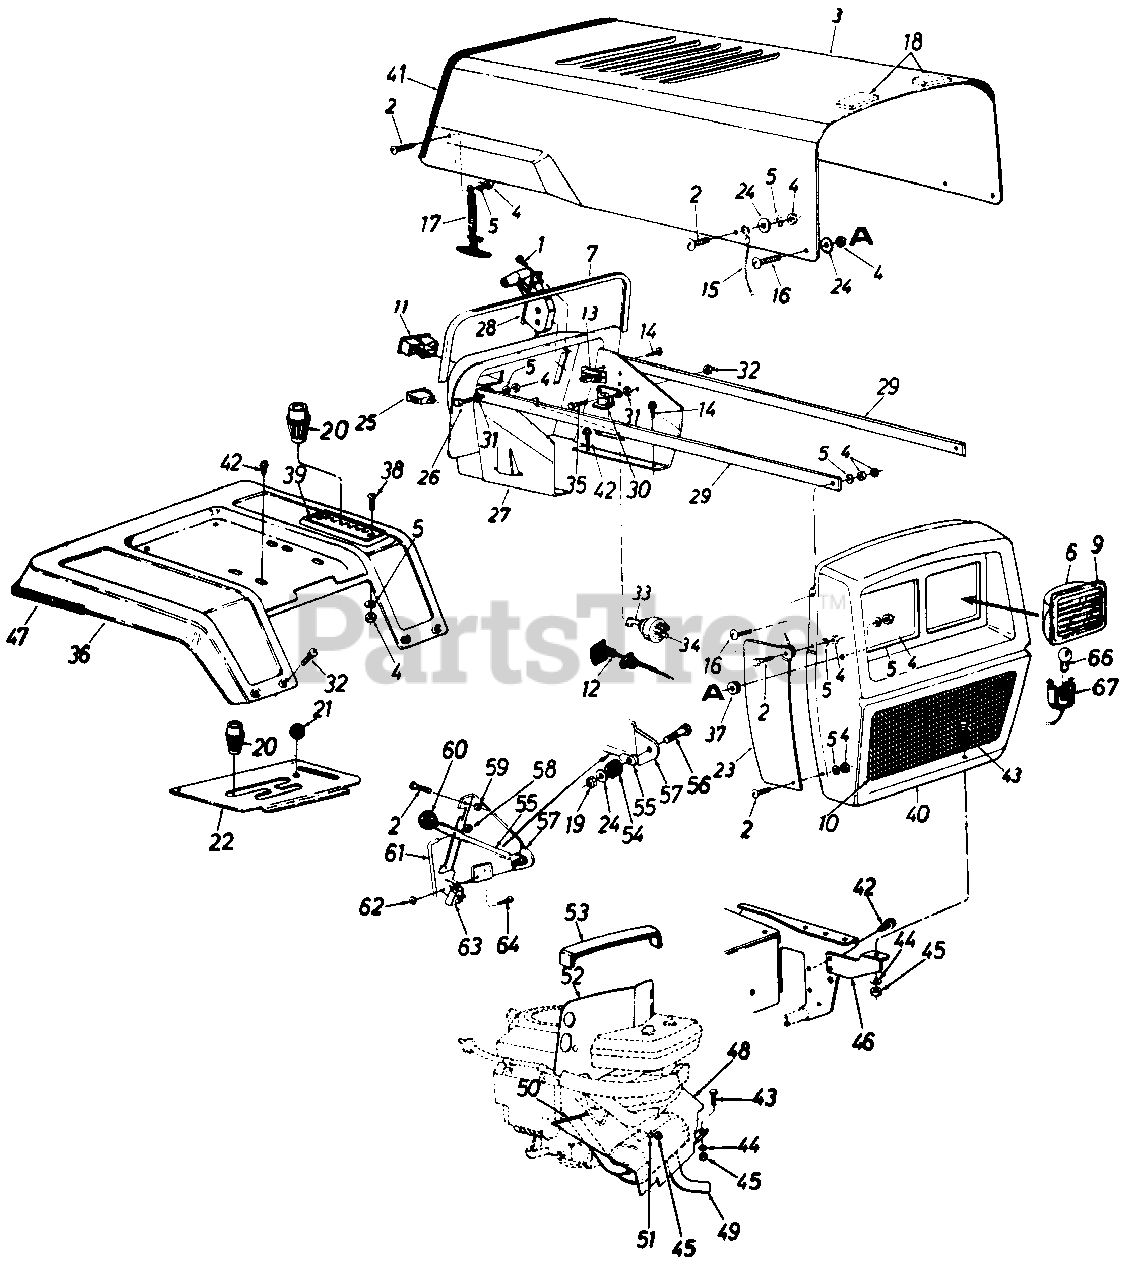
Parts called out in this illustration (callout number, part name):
1	N Truss Mach. AB-Tap Scr. #10 x .5" Lg.
2	Truss Mach. Scr. 1/4-20 x .S"
5	L-Wash. 1/4" I.D.
6	Headlight Housing
7	Trim Strip 31" Lg.
9	Headlight Lens
10	Grille Screen
11	Ammeter
12	Choke Control 46" Lg.
13	Circuit Breaker 8 Amp
14	Hex Tap Scr. #10 x .5" Lg.
15	Hood Stop
16	Truss Mach. Scr. 1/4-20 x .75"
17	Hood Latch Ass'y.
18	Foam Strip
19	Hex Patch L-Nut 1/4-20 Thd.
20	Shift Knob
21	Ball Knob Brake
22	Transmission Cover
23	Grille Side Panel R.H.
24	Fl-Wash. .281" I.D. x .73" O.D.
25	Light Switch
26	Truss Mach. Scr. 1/4-20 Thd.
27	Dash Panel Ass'y.
28	Throttle Control Box Ass'y.
29	Grille Support Rod
30	N Solenoid
31	Ext. L-Wash. 1/4" I.D.
32	Carriage Bolt 1/4-20 x .5" Lg.
33	Ignition Key
34	Ignition Switch
35	Hex Bolt 1/4-20 x .5" Lg.
36	Rear Fender
37	Rubber Washer
38	Truss Mach. Scr. 1/4-20 x .62"
39	7-Speed Index Brkt.
42	Hex Wash. AB-Tap Scr. 5/16 x .75" Lg.
43	Hex Bolt 5/16-18 x .75" Lg.
44	L-Wash. 5/16" I.D.
45	Hex Nut 5/16-18 Thd.
46	Grille Mtg. Bracket R.H.
47	Trim Strip 81" Lg.
48	Front Heat Shield
49	Muffler
50	Trim Strip 10" Lg.
51	Spec. L-Wash. 5/16" I.D.
52	Top Heat Shield
53	PVC Foam
54	Rubber Washer
55	PTO Lever
56	Hex Bolt 1/4-20 x 1.25" Lg.
57	Deck Clutch Control Brkt.
58	Push Cap
59	Hex Sems Nut 1/4-20 Thd.
60	Knob Blade Clutch
61	Deck Control Rod
62	Hex Nut #10-24 Thd.
63	Safety Switch
64	Truss Mach. Scr. #10-24 x .5"
66	Lamp
67	Socket
